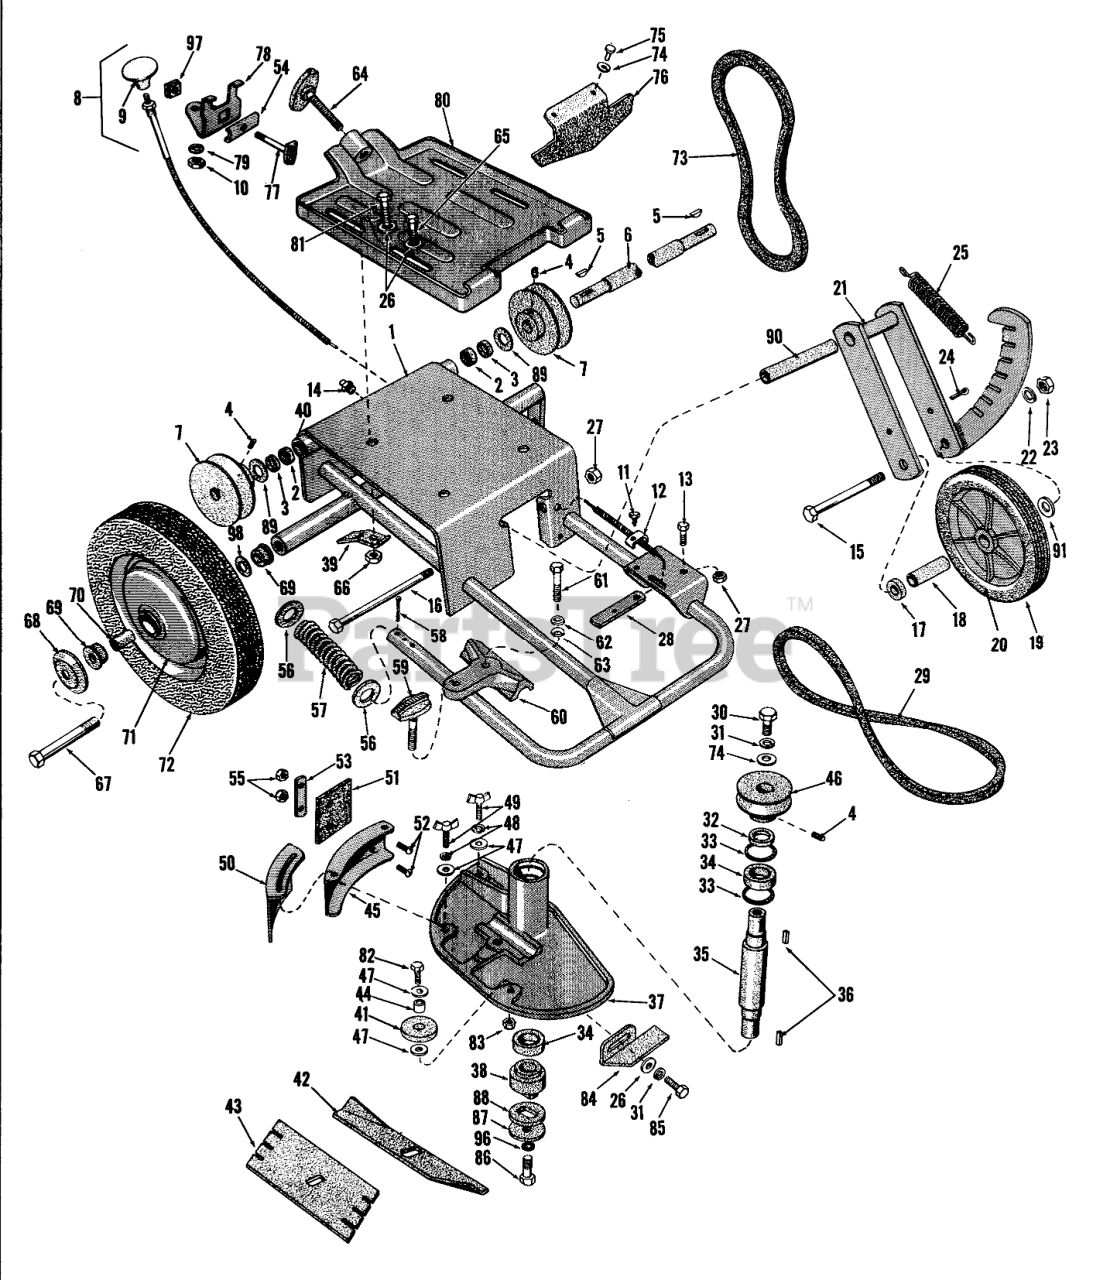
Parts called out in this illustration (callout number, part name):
2	Bearing
3	Oil Seal
4	SCREW-HSH
5	KEY-WOODRUFF
10	NUT-HJ
11	SCREW-HWH
12	CONTROL WIRE CLIP
13	SCREW-HH
14	FITTING-GREASE
15	SCREW-HH
16	Capscrew
19	Tires, 6"
20	Wheel w/Bushings, Ref. 39
22	WASHER-LOCK
23	NUT-HEX
24	PIN-COTTER
25	Spring
26	WASHER-PLAIN
27	NUT-LOCK NI
30	SCREW-HH
31	WASHER-LOCK
32	Spacer
34	Bearing
41	Trimming Roller
44	SPACER
47	WASHER-FLAT
48	WASHER-LOCK
49	1/4 - 20 3/4 WING SCR
52	SCREW-PPH
54	Strap
55	NUT-LOCK, NI
56	Washer
58	PIN-COTTER
61	SCREW-HH
62	U SPHER WASHER
63	L SPHER WASHER
64	Clamp Assy.
65	SCREW-HH
66	Nut
67	SCREW-HH
74	WASHER-FLAT
77	Clamp Assembly
79	WASHER-LOCK, INTERNAL
80	Adapter Plate
81	SCREW-HH
82	SCREW-HH
83	NUT-LOCK, NI
87	HUB WASHER
91	WASHER-FLAT
96	WASHER-LOCK, INTERNAL
97	Retaining Nut
